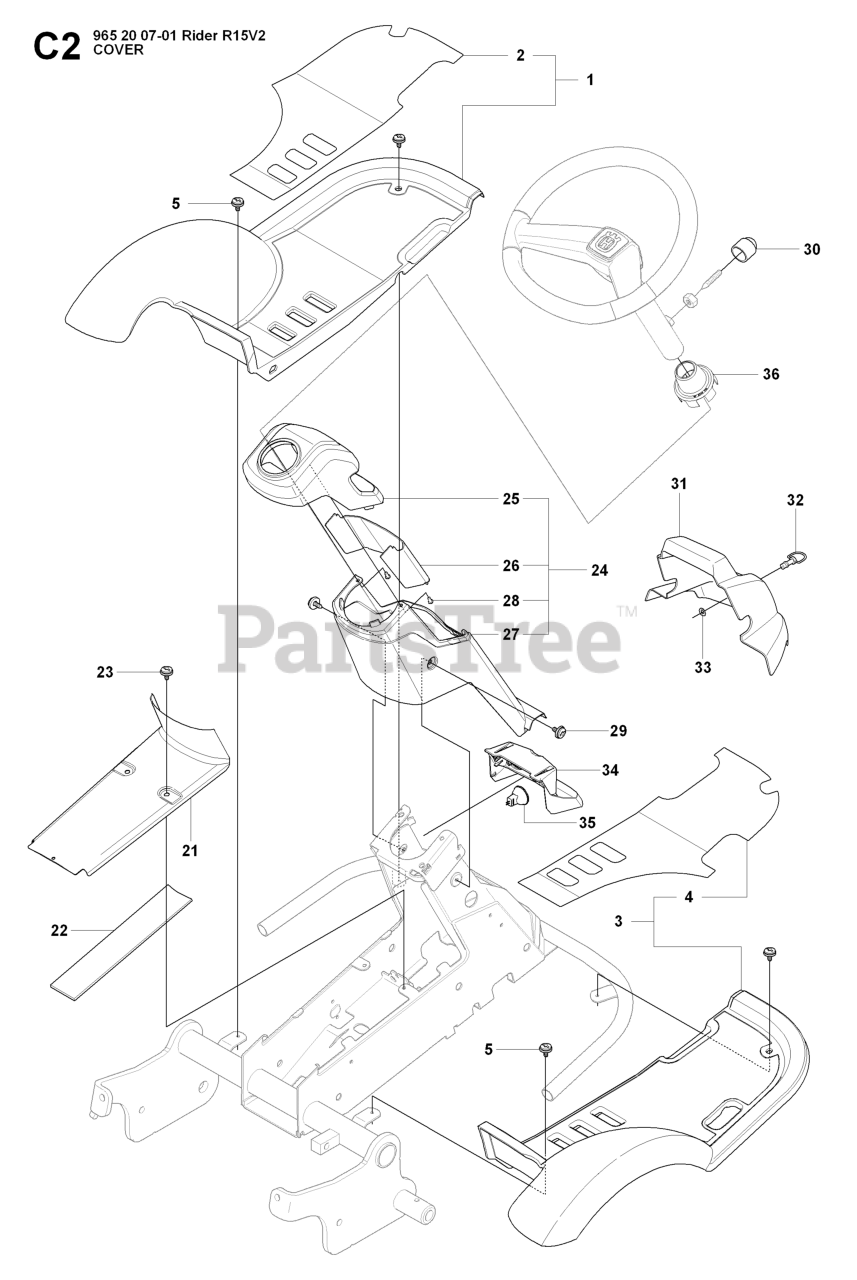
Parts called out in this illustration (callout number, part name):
1	FOOT PLATE
3	FOOT PLATE
30	PROTECTIVE COVER
32	BOLT
